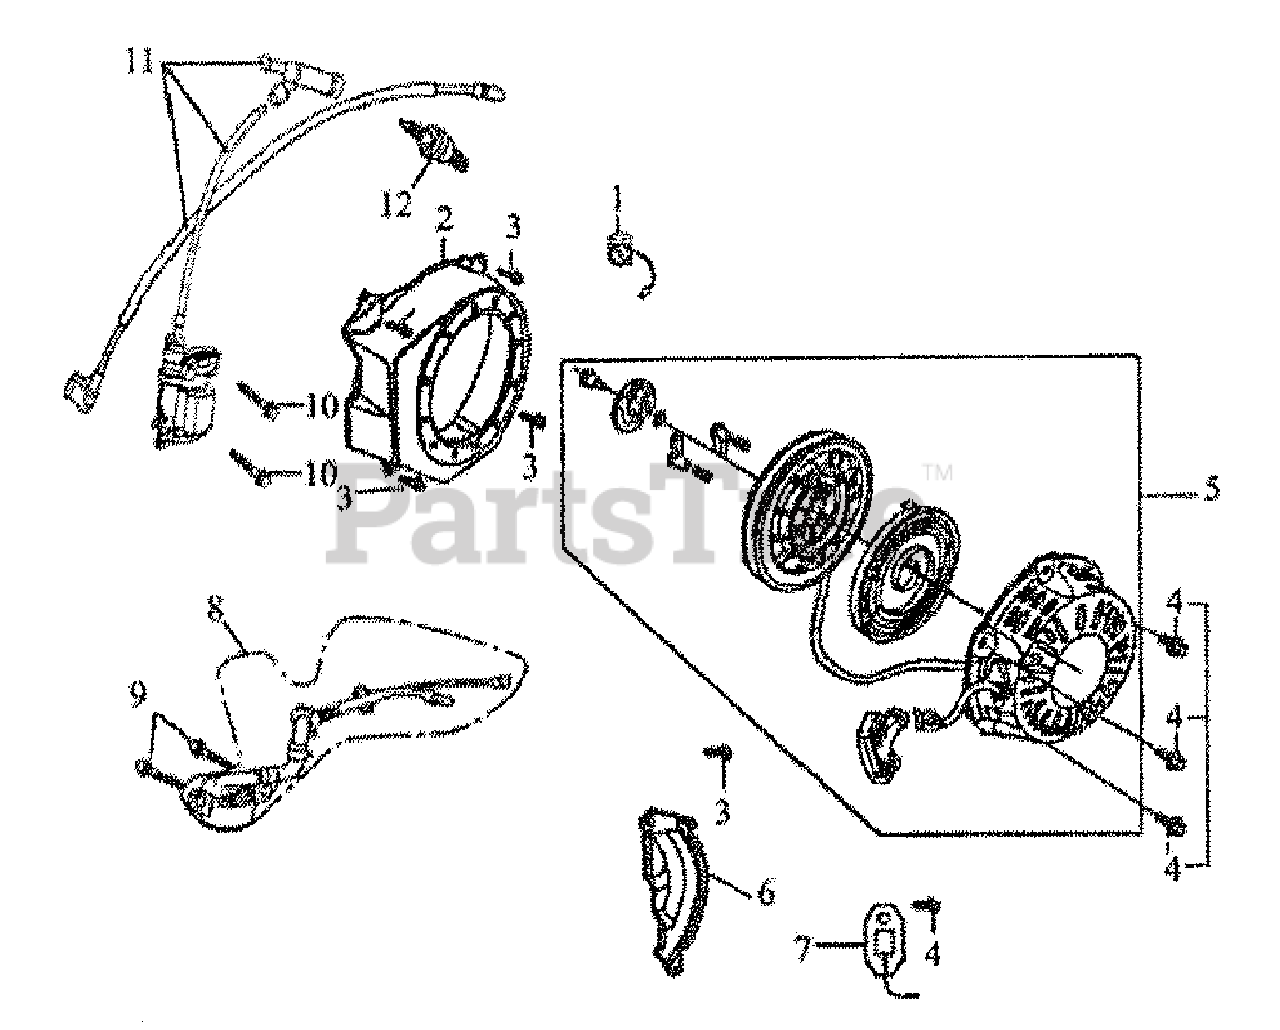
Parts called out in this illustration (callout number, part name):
1	SWITCH' ENGINE
2	HOOD' FAN
3	BOLT' M6X12
4	BOLT' M6X8
5	STARTER ASSY' RECOIL
6	SHROUD' COMPLETE
8	SENSOR' OIL
9	BOLT' M6X14
10	BOLT' M6X22
11	COIL ASSY' IGNITION
12	PLUG' SPARK
